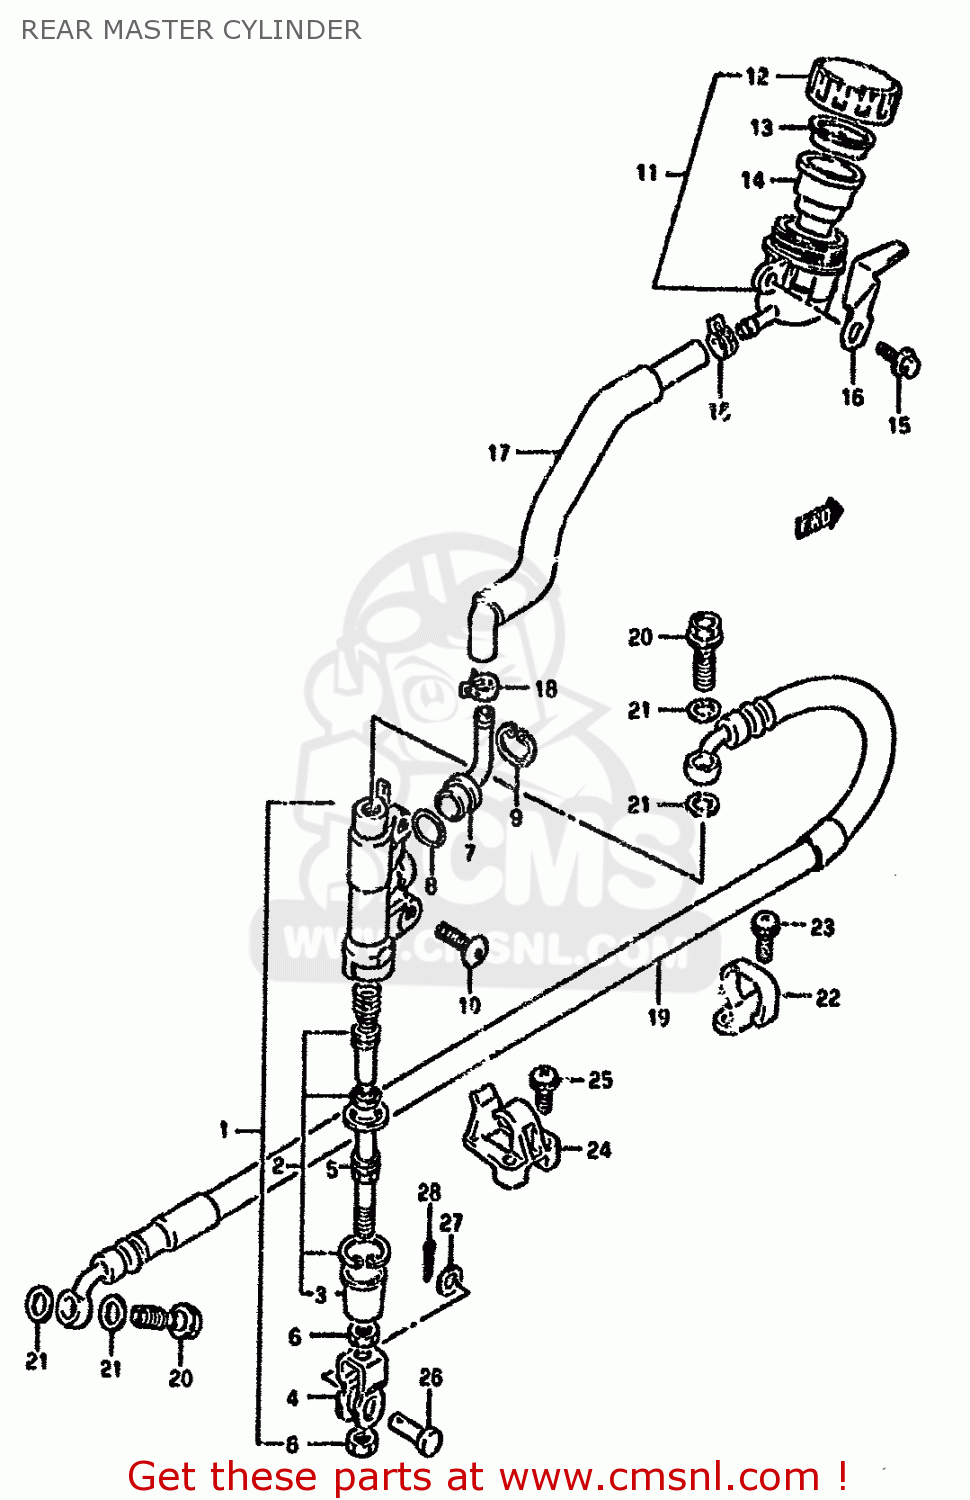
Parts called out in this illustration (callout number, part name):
1	CYLINDER ASSEMBLY,REAR MASTER
2	PISTON/CUP SET
3	BOOT
4	YOKE
5	ROD,PUSH
6	NUT
7	CONNECTOR
8	O RING
9	CIRCLIP
10	SCREW
11	TANK ASSY,RR BRAKE RESERVOIR
12	CAP
13	PLATE
14	DIAPHRAGM
15	BOLT
16	GUARD,RSVR TANK CAP
17	HOSE COMP,RESERVOIR TANK
18	CLIP
19	HOSE,RR BRAKE
20	BOLT UNION
21	WASHER(10X15X1.5)
22	GUIDE,RR BRAKE HOSE
23	SCREW
24	GUIDE,RR BRAKE HOSE
25	SCREW
26	PIN(8X20)
27	WASHER(8.5X13X1.6)
28	PIN 20X15
